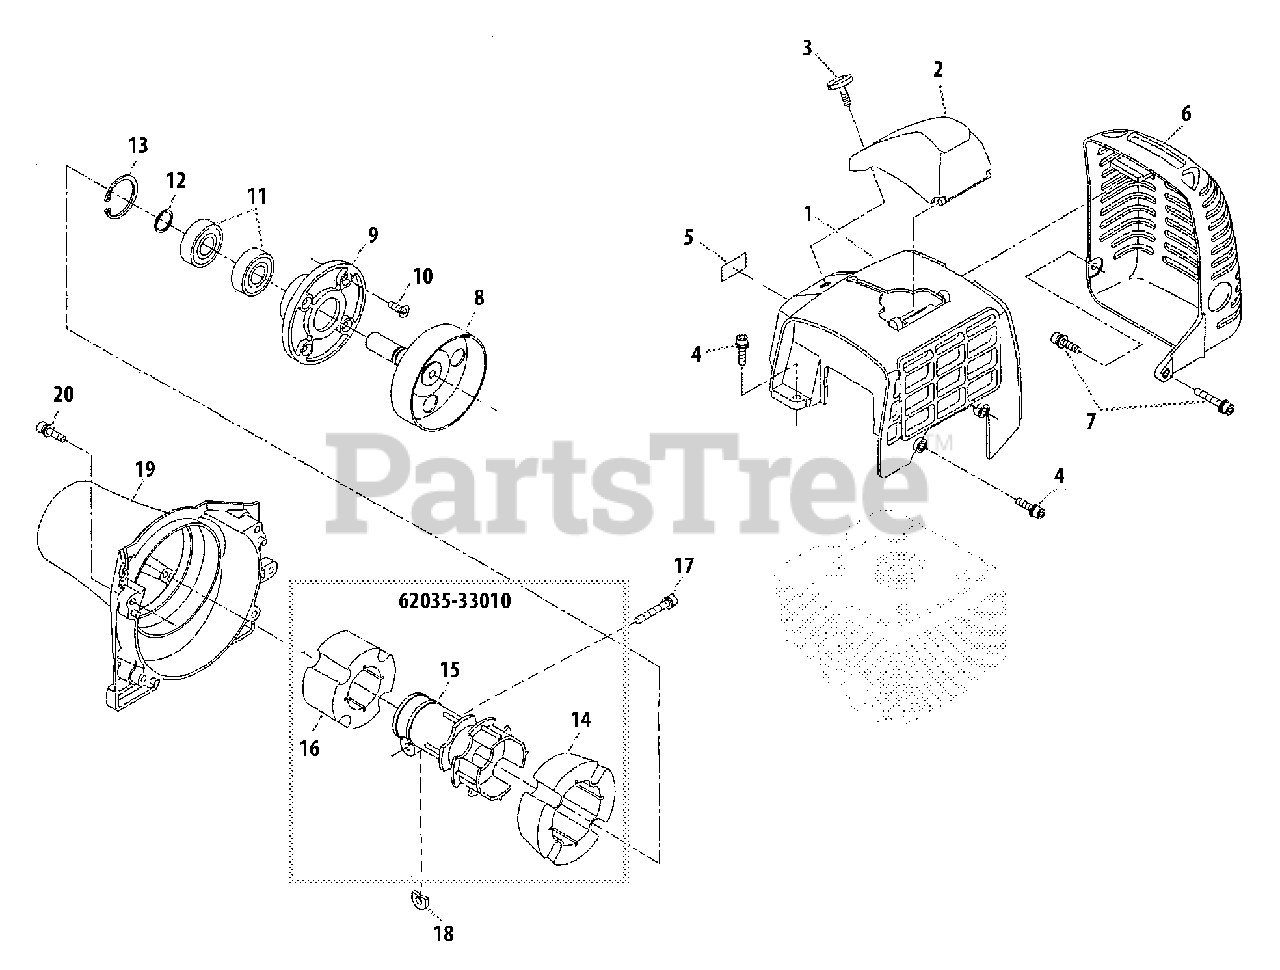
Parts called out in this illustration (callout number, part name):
1	COVER, ENGINE
2	COVER, SPARK PLUG
3	THUMBSCREW
4	BOLT M5×16
5	LABEL
6	MUFFLER, COVER
7	BOLT M5×16
8	DRUM, CLUTCH
9	CASE, CLUTCH
10	SCREW M5×16
11	BEARING, BALL 6202 DDU
12	RING, SNAP
13	RING, SNAP Ø35
14	CUSHION, REAR
15	JOINT
16	CUSHION, FRONT
17	BOLT M6×28
18	SHIM
19	COVER, FAN
20	BOLT SS M5×30
62035-33010	JOINT ASSY
